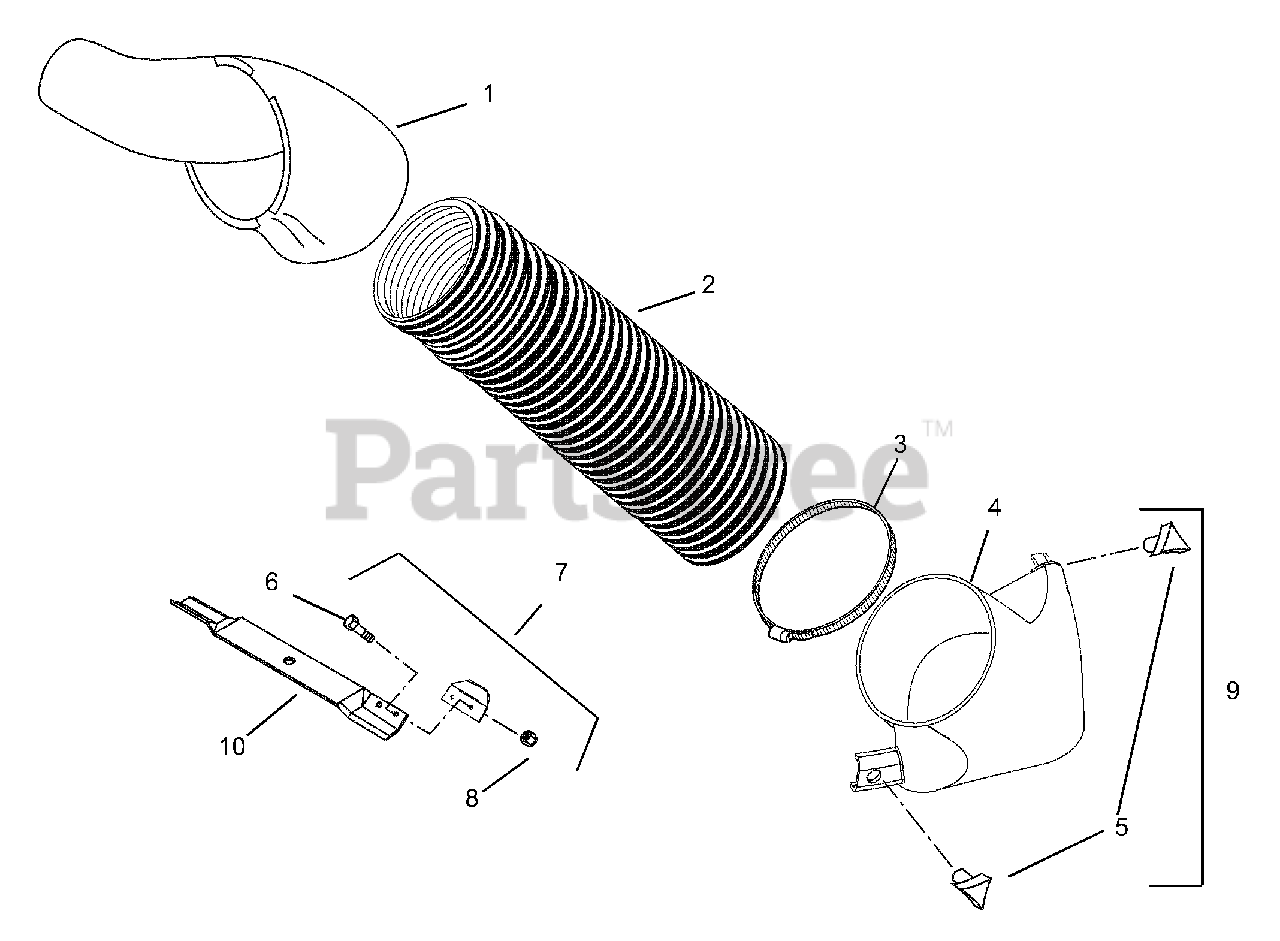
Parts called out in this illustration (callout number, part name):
1	BAGGER BOOT
2	HOSE 7X38
3	CLAMP-HOSE WRM 2.13/8.62X.56
4	ASS'Y, MOWER BOOT W/DECAL
6	BLT-HEX .31-24X.75 GR8 YWZC
7	ASS'Y, VANE SERVICE
8	NUT-CTRLK .31-24 YWZC
9	ASS'Y, MOWER BOOT 42"
10	BLADE, 22"
